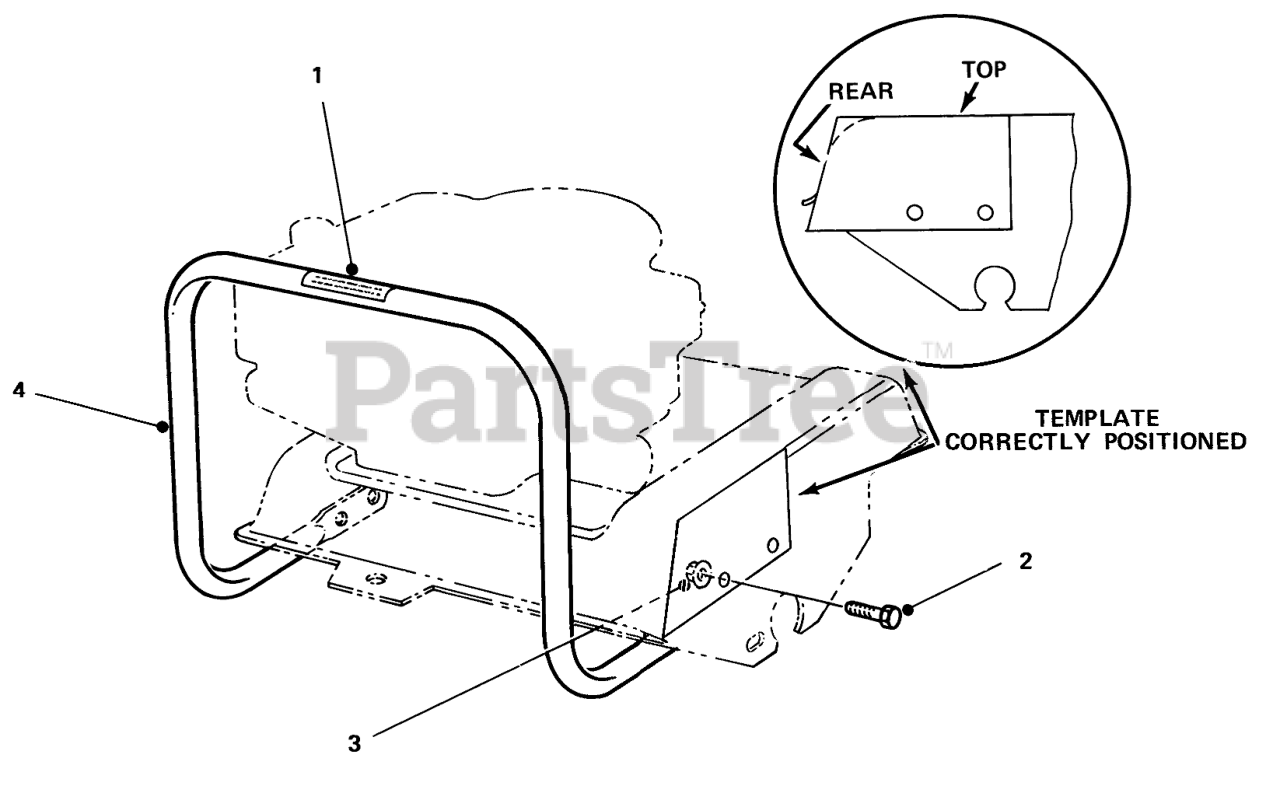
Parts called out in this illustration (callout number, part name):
1	Caution Decal
2	SCREW-HH
3	Nut
4	Standbar
